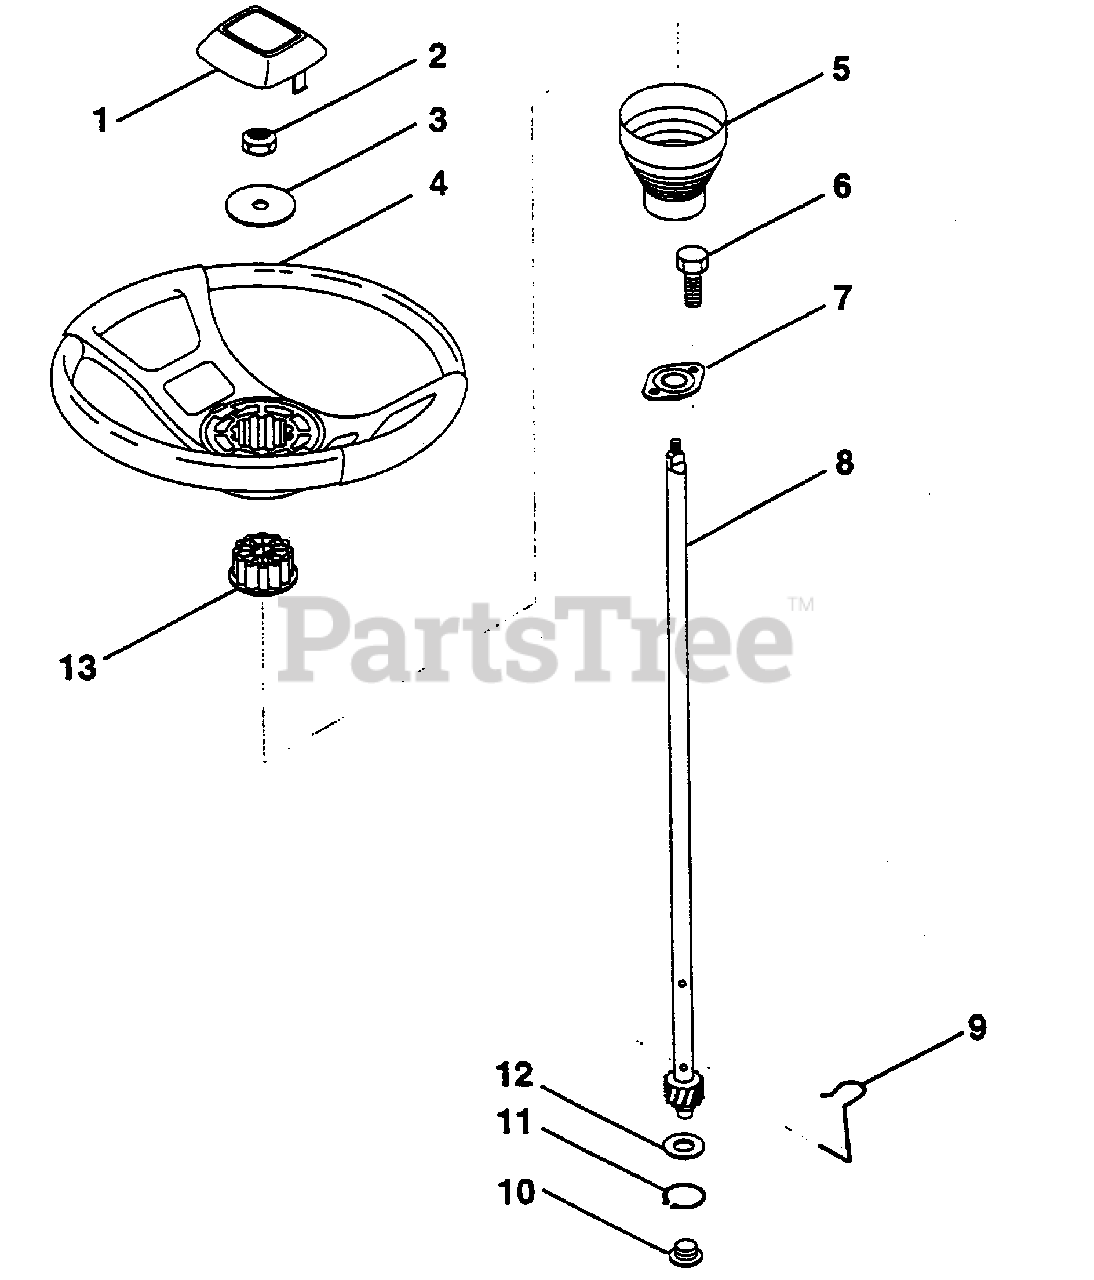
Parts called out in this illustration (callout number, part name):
1	Insert, Steering Wheel (AYP part number)
2	Locknut 3/8-24 UNF (AYP part number)
3	Washer 12/32 x 2-3/8 x 8 Gauge (AYP part number)
4	Steering Wheel (AYP part number)
5	Sleeve, Steering (AYP part number)
6	Screw, Hex #10-16 x 1/2 TY-B (AYP part number)
7	Bushing, Steering (AYP part number)
8	Shaft, Steering (AYP part number)
9	Clip, Steering (AYP part number)
10	Bushing, Lower, Steering (AYP part number)
11	Ring, Retaining (AYP part number)
12	Washer 21/32 x 1 x 16 Gauge (AYP part number)
13	Adaptor, Steering Wheel (AYP part number)
